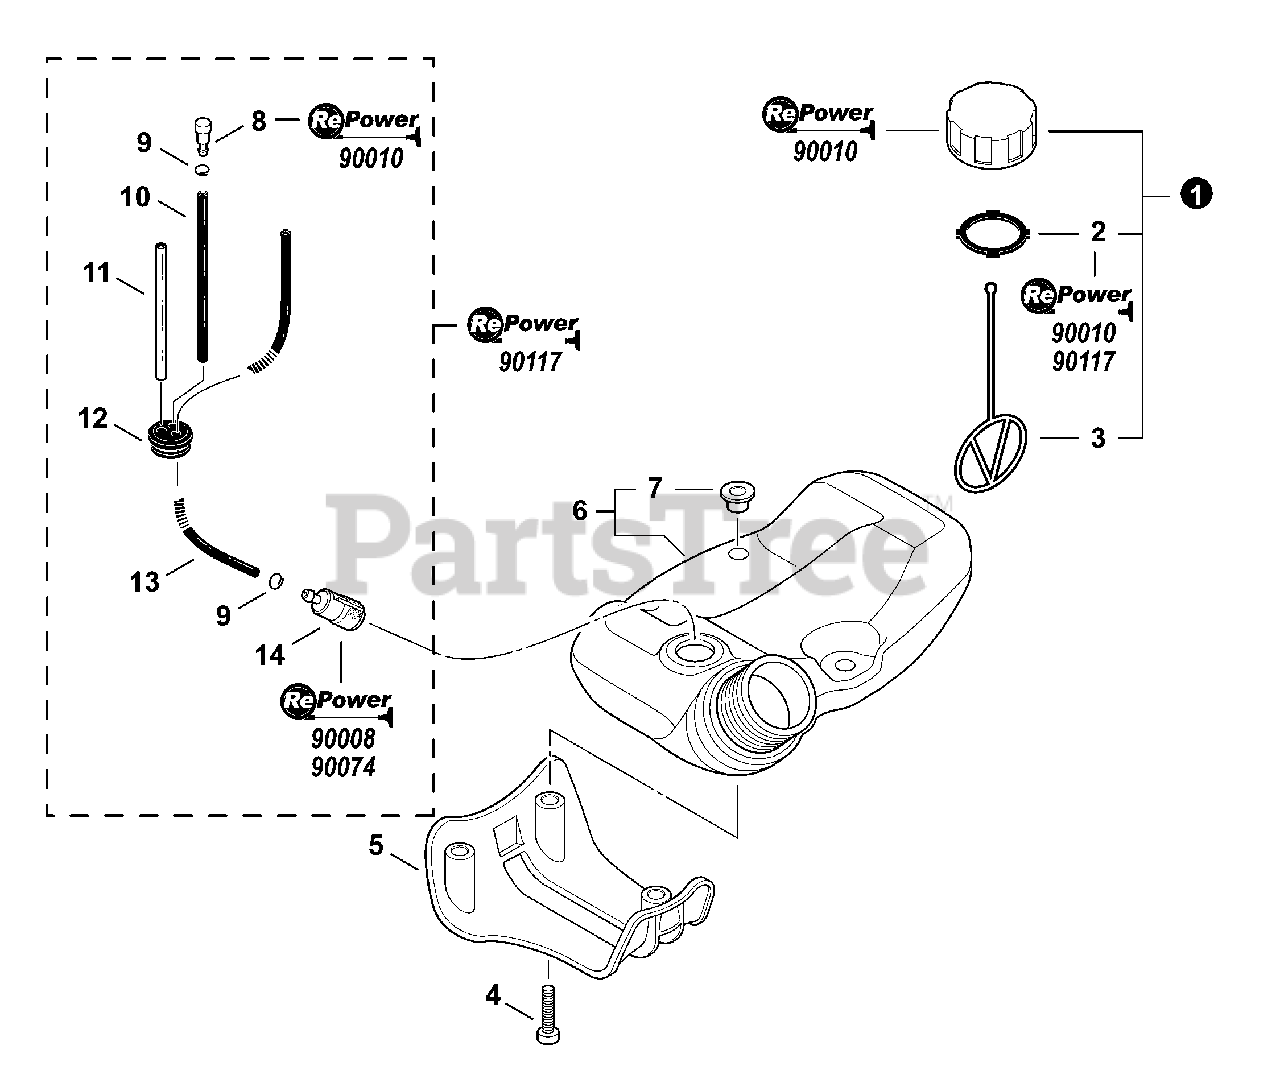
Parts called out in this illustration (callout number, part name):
1	CAP ASSY
2	GASKET, CAP
3	CONNECTOR, CAP
4	SCREW - 5×25
5	GUARD, FUEL TANK
6	FUEL TANK ASSY
8	VENT, FUEL TANK
9	CLIP - 6
10	PIPE - 3×5×90 -- BLACK
11	PIPE - 3×6×80 -- CLEAR
12	GROMMET
13	PIPE - 3×5×210 -- BLACK
14	FILTER, FUEL
